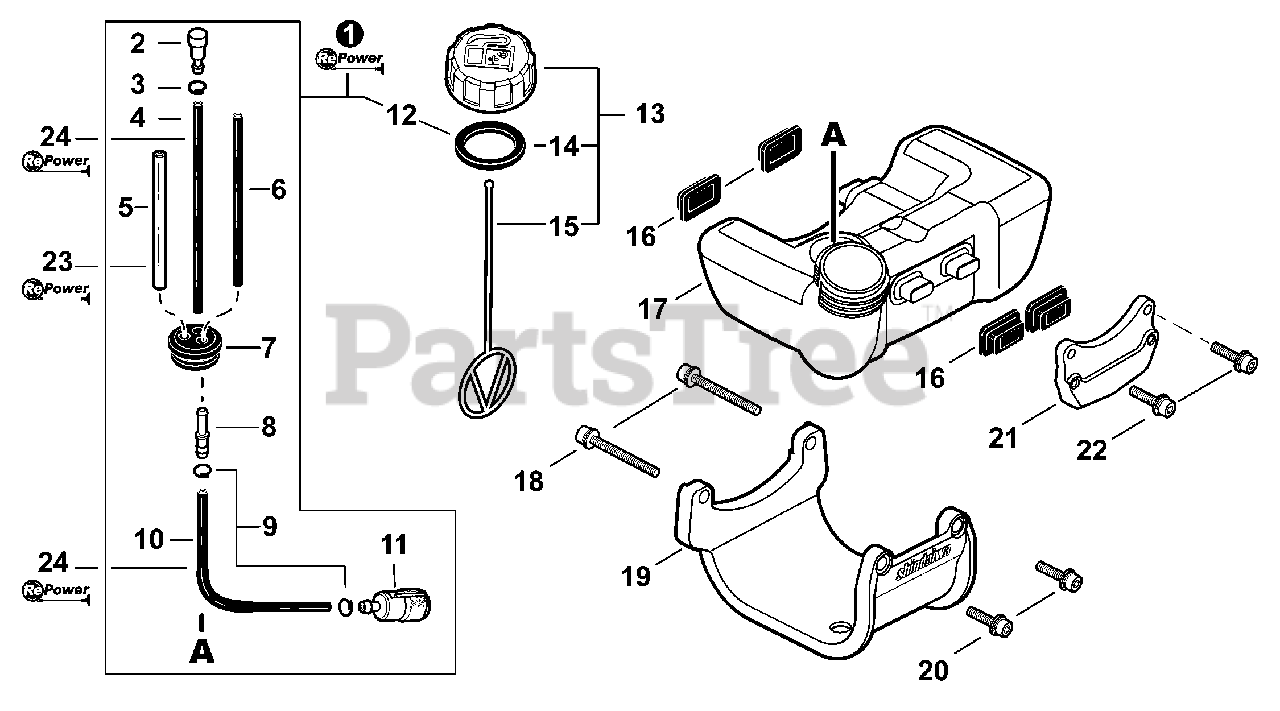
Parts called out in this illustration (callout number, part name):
1	FUEL SYSTEM KIT - REPOWER
2	VENT ASSY
3	CLIP 6.5MM
4	PIPE, FUEL 3×6×115 BLACK
5	PIPE, FUEL RETURN 3×6×90mm
6	PIPE, FUEL 3×5×78
7	GROMMET, FUEL
8	CONNECTOR, PIPE 5×3.5
10	PIPE, FUEL 3×6×120 BLACK
11	FILTER, FUEL 125-528
12	GASKET, FUEL CAP
13	CAP ASSY, FUEL
14	GASKET, FUEL CAP
15	CONNECTOR, CAP L= 123
16	CUSHION, FUEL TANK
17	TANK, FUEL
18	BOLT M5×40
19	GUARD, PLASTIC FUEL TANK
20	BOLT M5×20
21	BRACKET, METAL FUEL TANK
22	BOLT, ADHESIVE M5×20
23	PIPE, FUEL - REPOWER BULK 3×6mm CLEAR
24	PIPE, FUEL - REPOWER BULK 3×6mm BLACK
